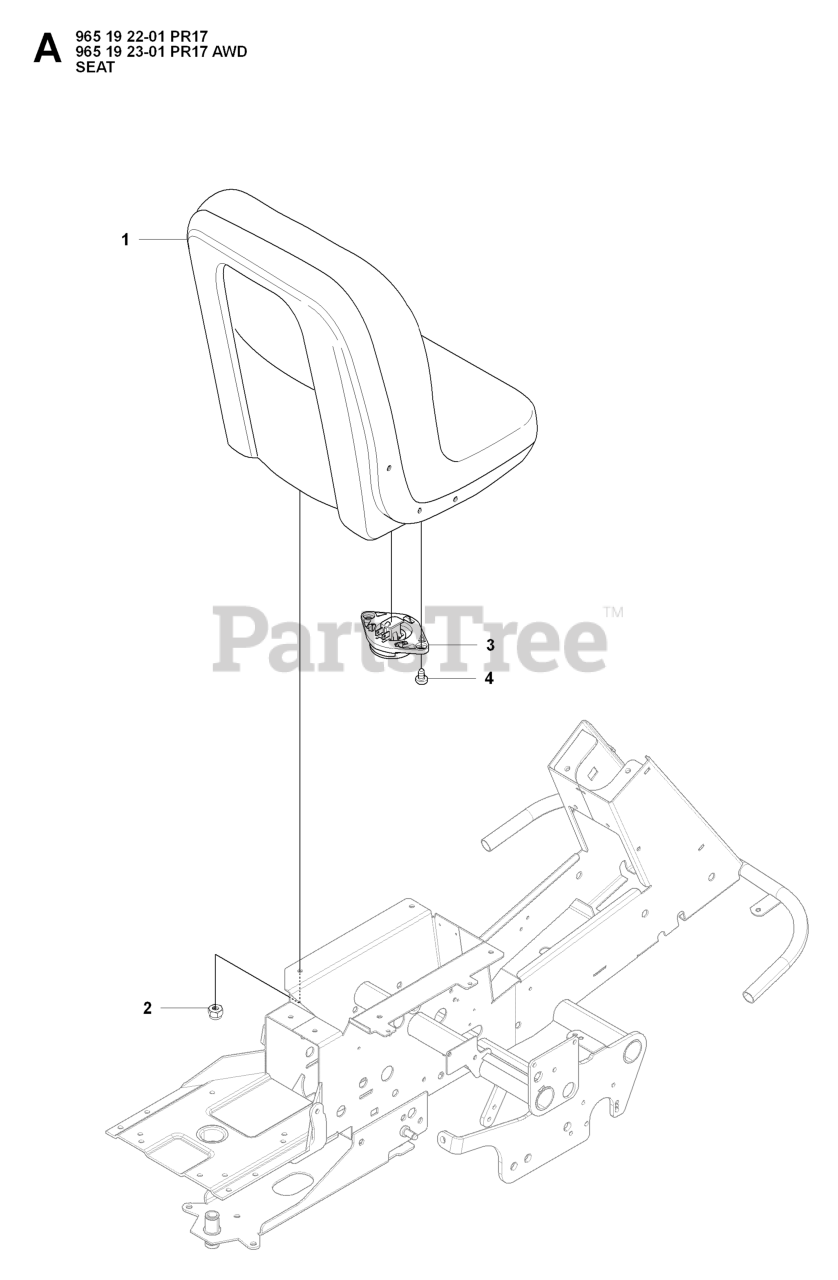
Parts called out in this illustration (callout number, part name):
2	LOCKNUT M8
3	ANTI-START SWITCH CPL
4	SCREW
